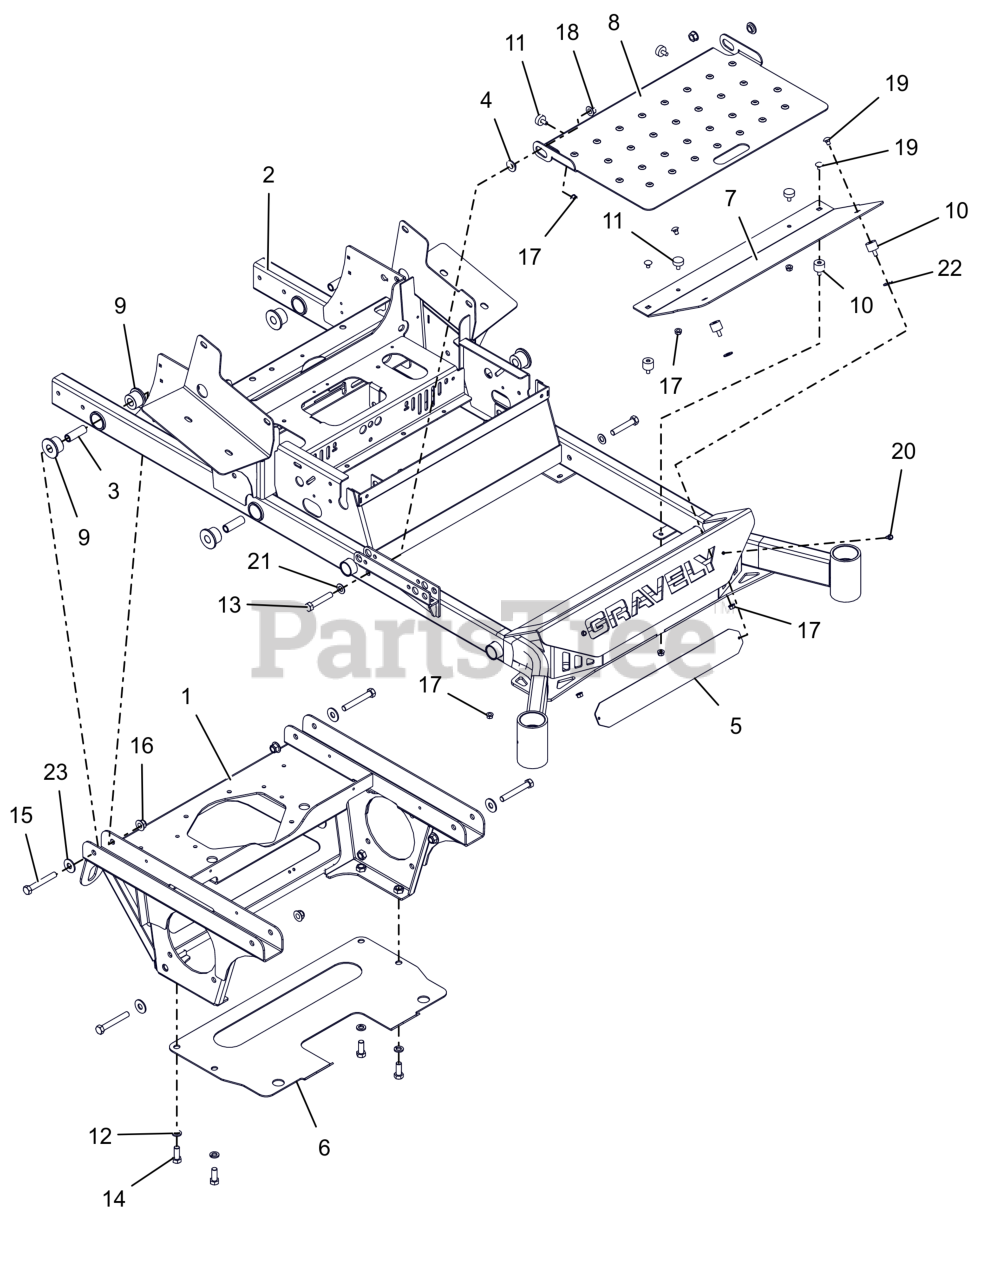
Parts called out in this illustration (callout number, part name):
1	PT200/400 AXLE/ENG FRM WMT-RED
2	52-60"PT200/400 FRAME W/DECALS
3	BSHG-SLV .50X.75X2.23
4	BSHG-FLG .515X.750X.310X1.120
5	BUMPER LOGO BACKING PLATE -BLK
6	PLATE-TRANSMISSION SKID
7	FOOTREST, (RED)
8	INSPECTION PANEL W/SAFE DECAL
9	BSHG-FLG .75X1.51X1.13X2.0 URE
10	BUMPER,STUD MNTD W/FEMALE INSR
11	BUMPER, RUBBER
12	WSHR,LK-REG .500X.125 ZCC
13	BLT,HEX .50-13X2.75 G5 ZCC
14	BLT,HEX .50-13X1.25 G5 ZCC
15	BLT, HEX .50-13X3.50 G5 ZCC
16	NUT,NYL-FLG .50-13 GF ZCC
17	NUT,SPNLK-FLG .31-18 G5 ZCC
18	NUT-LK-CTR-FLG .500-13 GG ZCC
19	BTL,RHSN .313-18 X 0.5 G5 ZCC
20	SCR-TAP .25-20X.50 HWH ZCC
21	WSHR, FLT .531X1.00X.063 ZCC
22	WSHR,FLT .375X.875X.083 ZCC
23	WSHR,FLT .563X1.375X.109 ZCC
